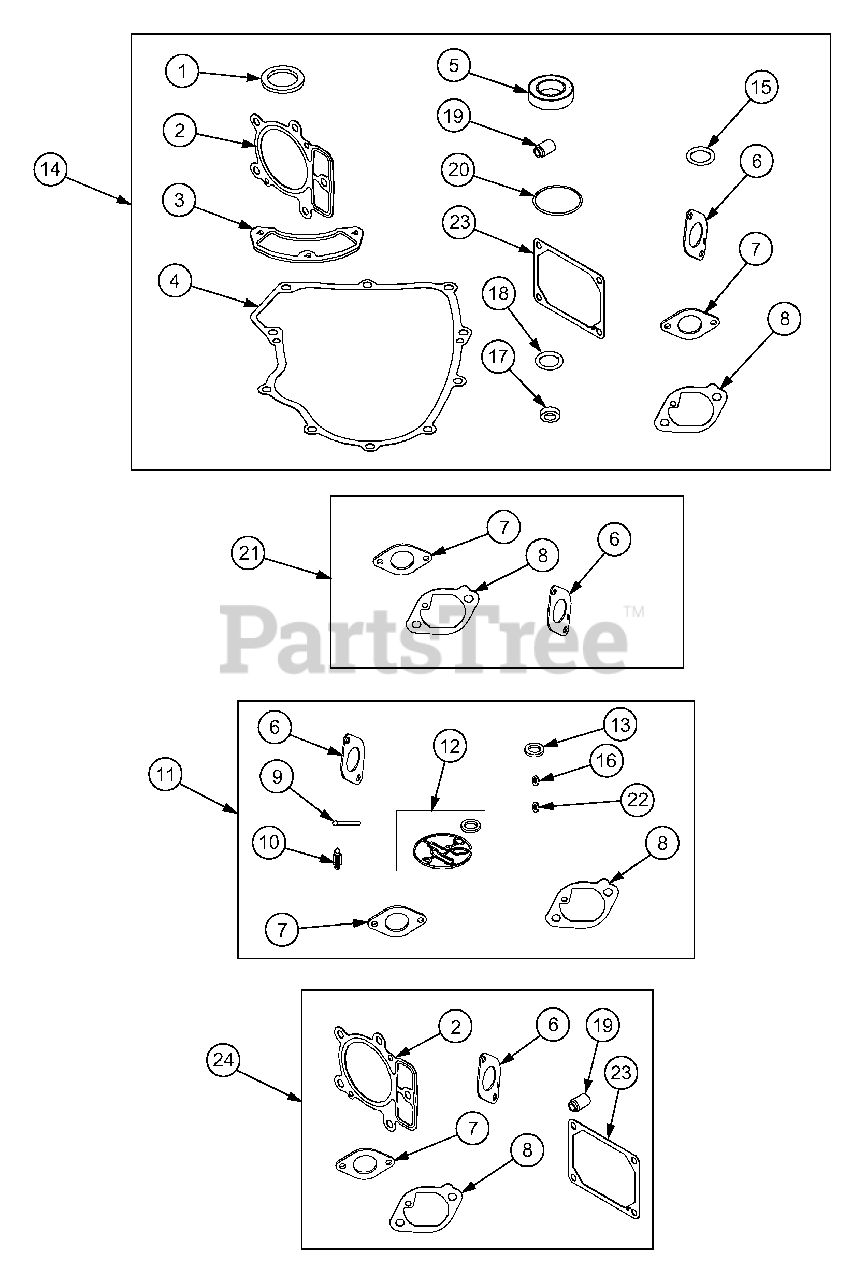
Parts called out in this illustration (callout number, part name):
1	Seal, Oil
2	Gasket, Cylinder Head
3	Gasket, Breather
4	Gasket, Crankcase
5	Seal, Oil
6	Gasket, Intake
7	Gasket, Intake
8	Gasket, Intake
9	Pin, Float Hinge
10	Valve, Float Needle
11	Kit, Carburetor Overhaul
12	Gasket, Float Bowl
13	Washer, Sealing
14	Set, Engine Gasket
15	Seal, Dipstick Tube
16	Seal, Choke/Throttle Shaft
17	Seal, Governor Shaft
18	Seal, Dipstick/Tube
19	Seal, Valve
20	Seal, O-Ring
21	Gasket Set, Carburetor
22	Seal, Throttle Shaft
23	Gasket, Rocker Cover
24	Gasket Set, Valve
